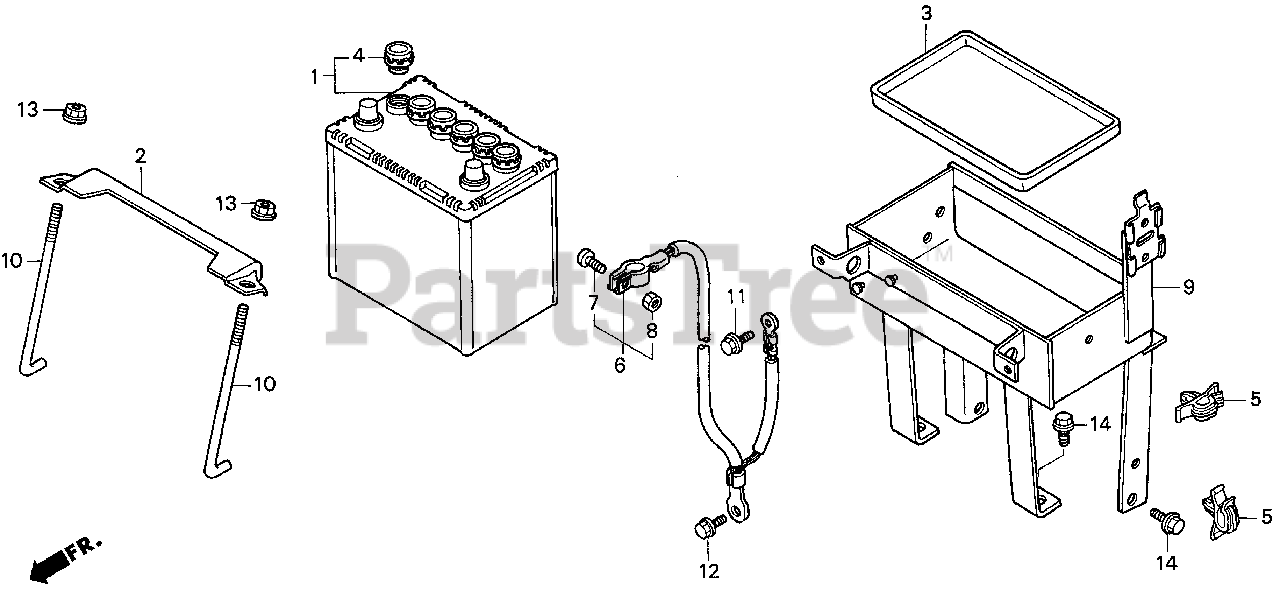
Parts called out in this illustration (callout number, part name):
1	BATTERY ASSY. (32A19RT-S) (YUASA)
2	PLATE, BATTERY SET
3	BOX, BATTERY
4	PLUG, VENT
5	CLIP, WIRE HARNESS
6	CABLE ASSY., GROUND
7	BOLT, BATTERY TERMINAL
8	NUT, BATTERY TERMINAL
9	HOLDER, BATTERY
10	BOLT, BATTERY SETTING
11	BOLT, FLANGE (6X14)
12	BOLT, GROUND (6X16) (SN)
13	NUT, FLANGE (6MM)
14	BOLT, FLANGE (10X22)
